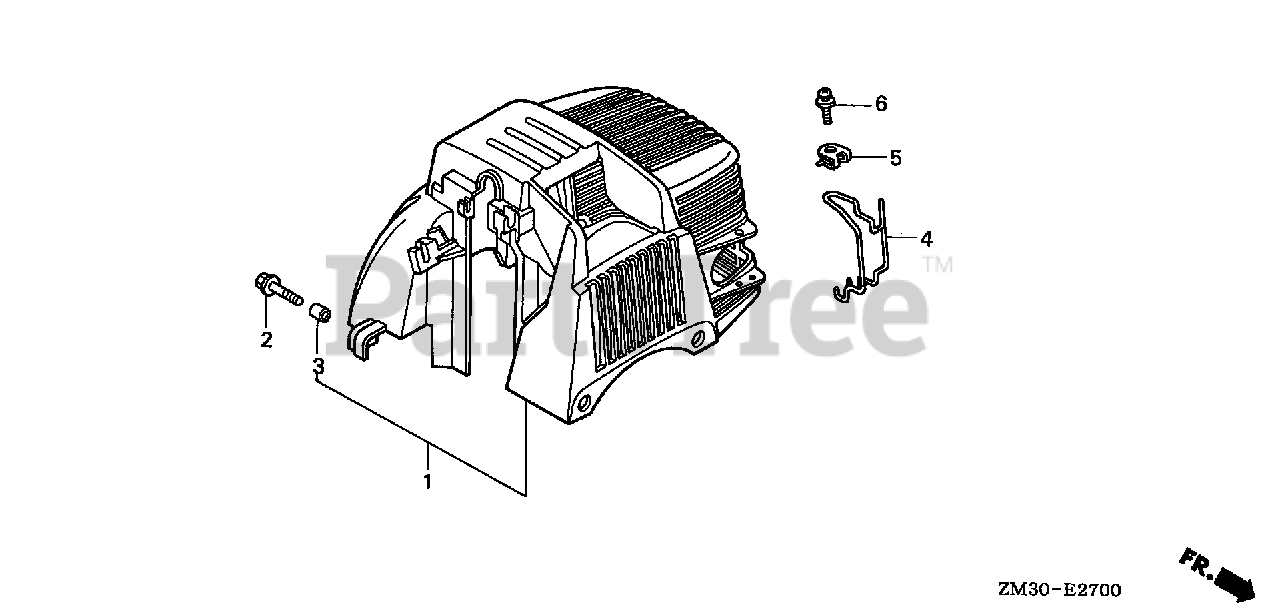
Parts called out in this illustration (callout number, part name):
1	COVER, TOP *R280* (POWER RED)
2	BOLT, FLANGE (5X22)
3	COLLAR, TOP COVER
